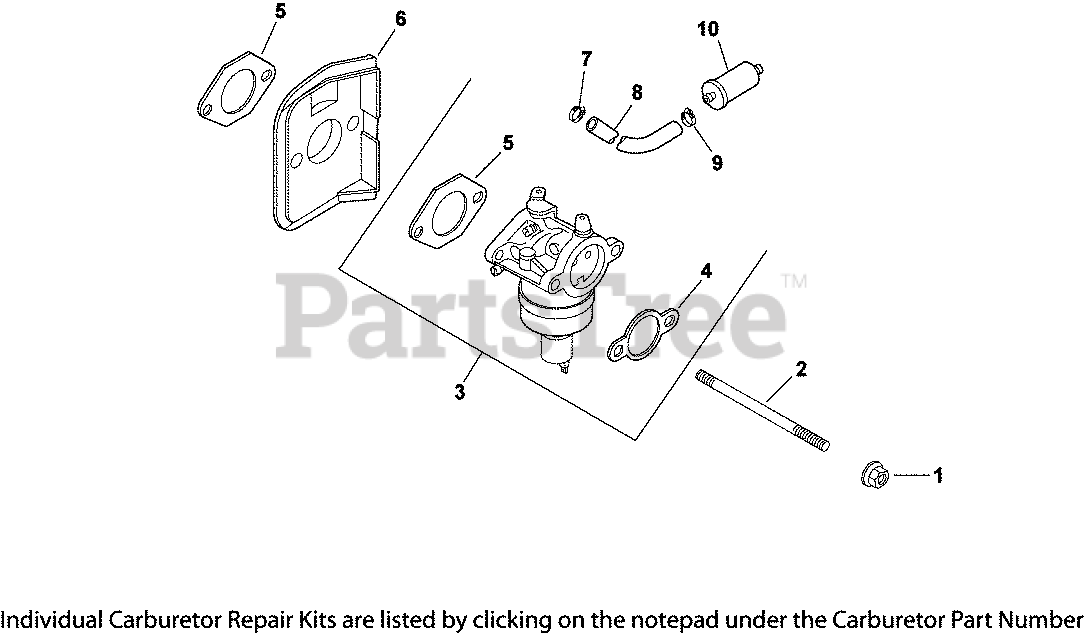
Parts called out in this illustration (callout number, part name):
1	NUT, FLG M6X1.0
2	STUD,M6X1.0X122
3	KIT, CARBURETOR w/GASKETS
4	GASKET, AIR CLEANER BASE
5	GASKET, CARBURETOR
6	DEFLECTOR, HEAT
7	CLAMP, HOSE (KM)-USE 25 237 31-S
8	HOSE,LW PERM.FUEL 24.00"-USE 25 111 81-S
9	CLAMP, BAND SPRING HOSE-(#2523737S)
10	FILTR,FUEL 75 MICRON (GRAVTY FEED)
